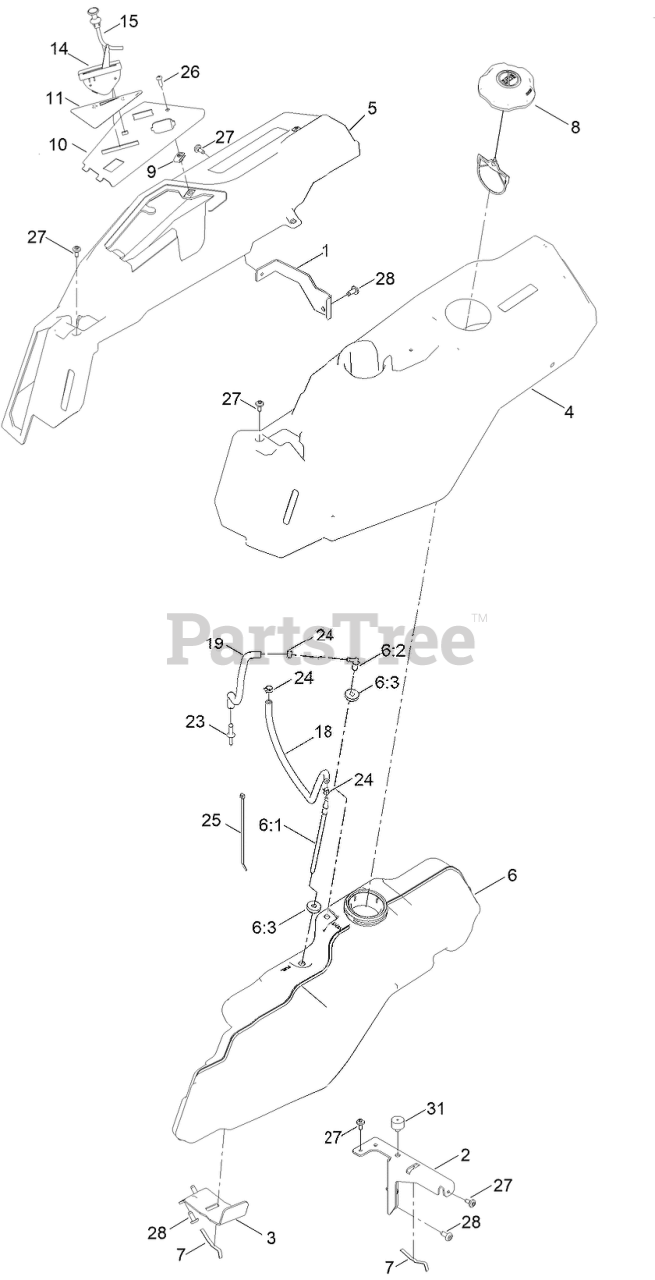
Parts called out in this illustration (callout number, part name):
1	BRACKET-POD
2	SUPPORT-POD, LH
3	SUPPORT-TANK, FUEL
4	POD-LH
5	POD-RH, MYRIDE
6	FUEL TANK ASM
6:1	CONNECTOR-ELBOW, 90 DEG
6:2	FITTING-PLASTIC
6:3	BUSHING
7	SPRING
8	CAP-FUEL, RATCHETING
10	PANEL - CONTROL
11	DECAL-PANEL, CONTROL
14	CABLE-THROTTLE
15	CABLE-CHOKE
18	HOSE-FUEL
19	HOSE-FUEL
23	ADAPTOR-ORIFICE
24	CLAMP-HOSE
25	TIE-CABLE
26	SCREW-PRH
27	SCREW-SHOULDER
31	BUMPER-GROMMET
